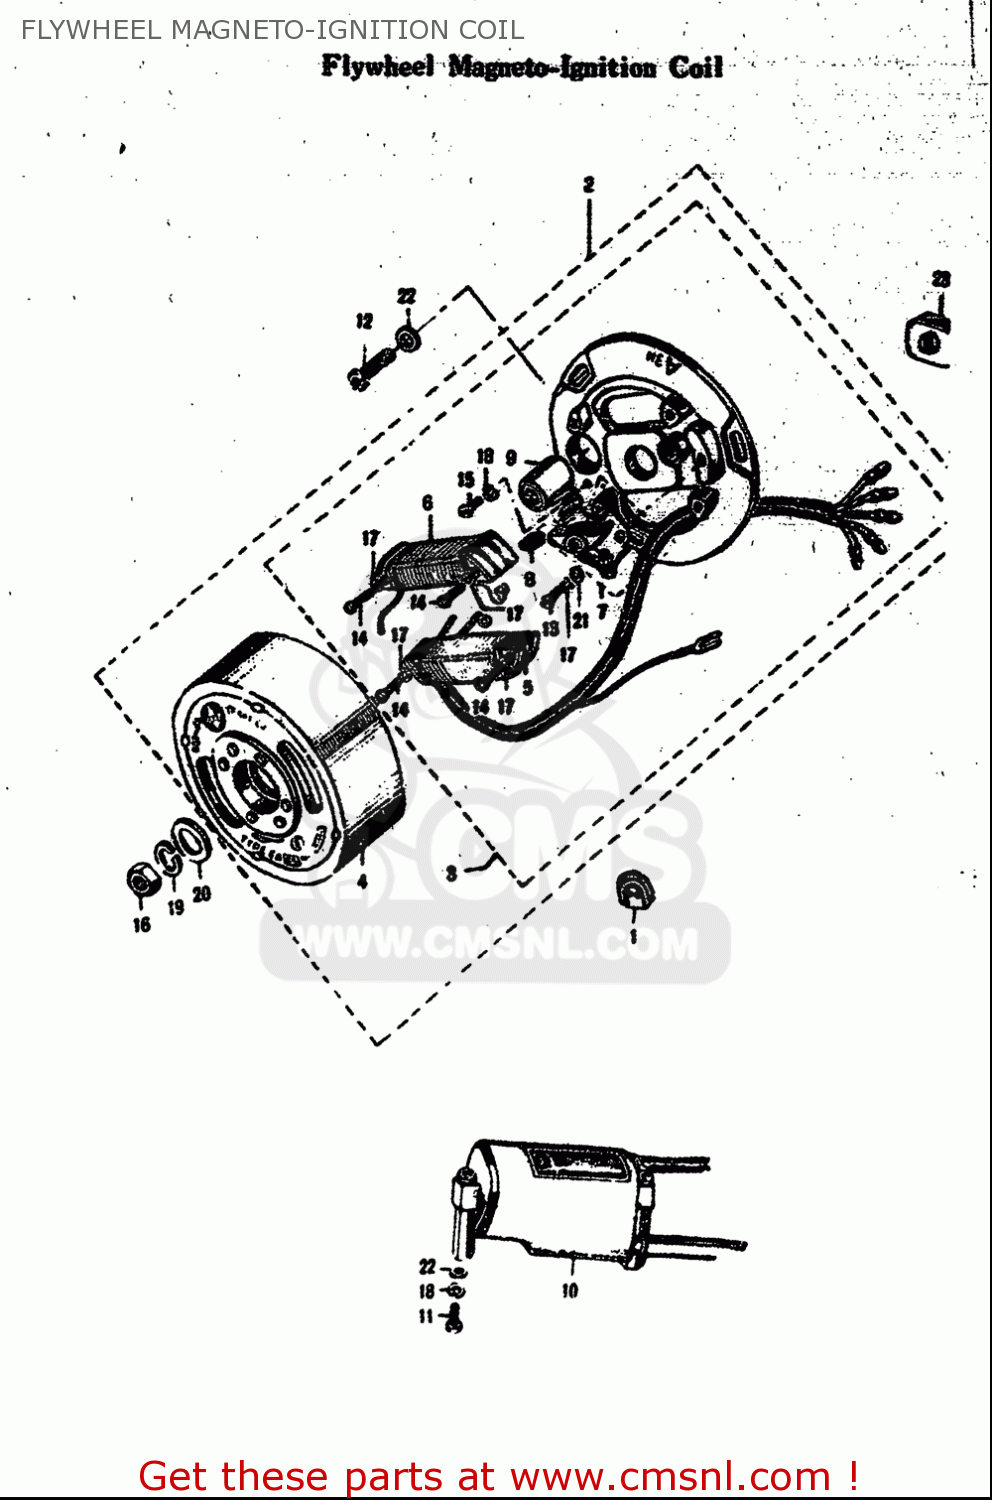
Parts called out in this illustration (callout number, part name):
7	POINT ASSY,CONTACT
9	CONDENSER
11	SCREW
12	SCREW
13	SCREW
15	.SCREW
16	NUT
17	WASHER,LOCK
18	WASHER,LOCK
19	WASHER,LOCK
20	WASHER
21	WASHER
22	WASHER
